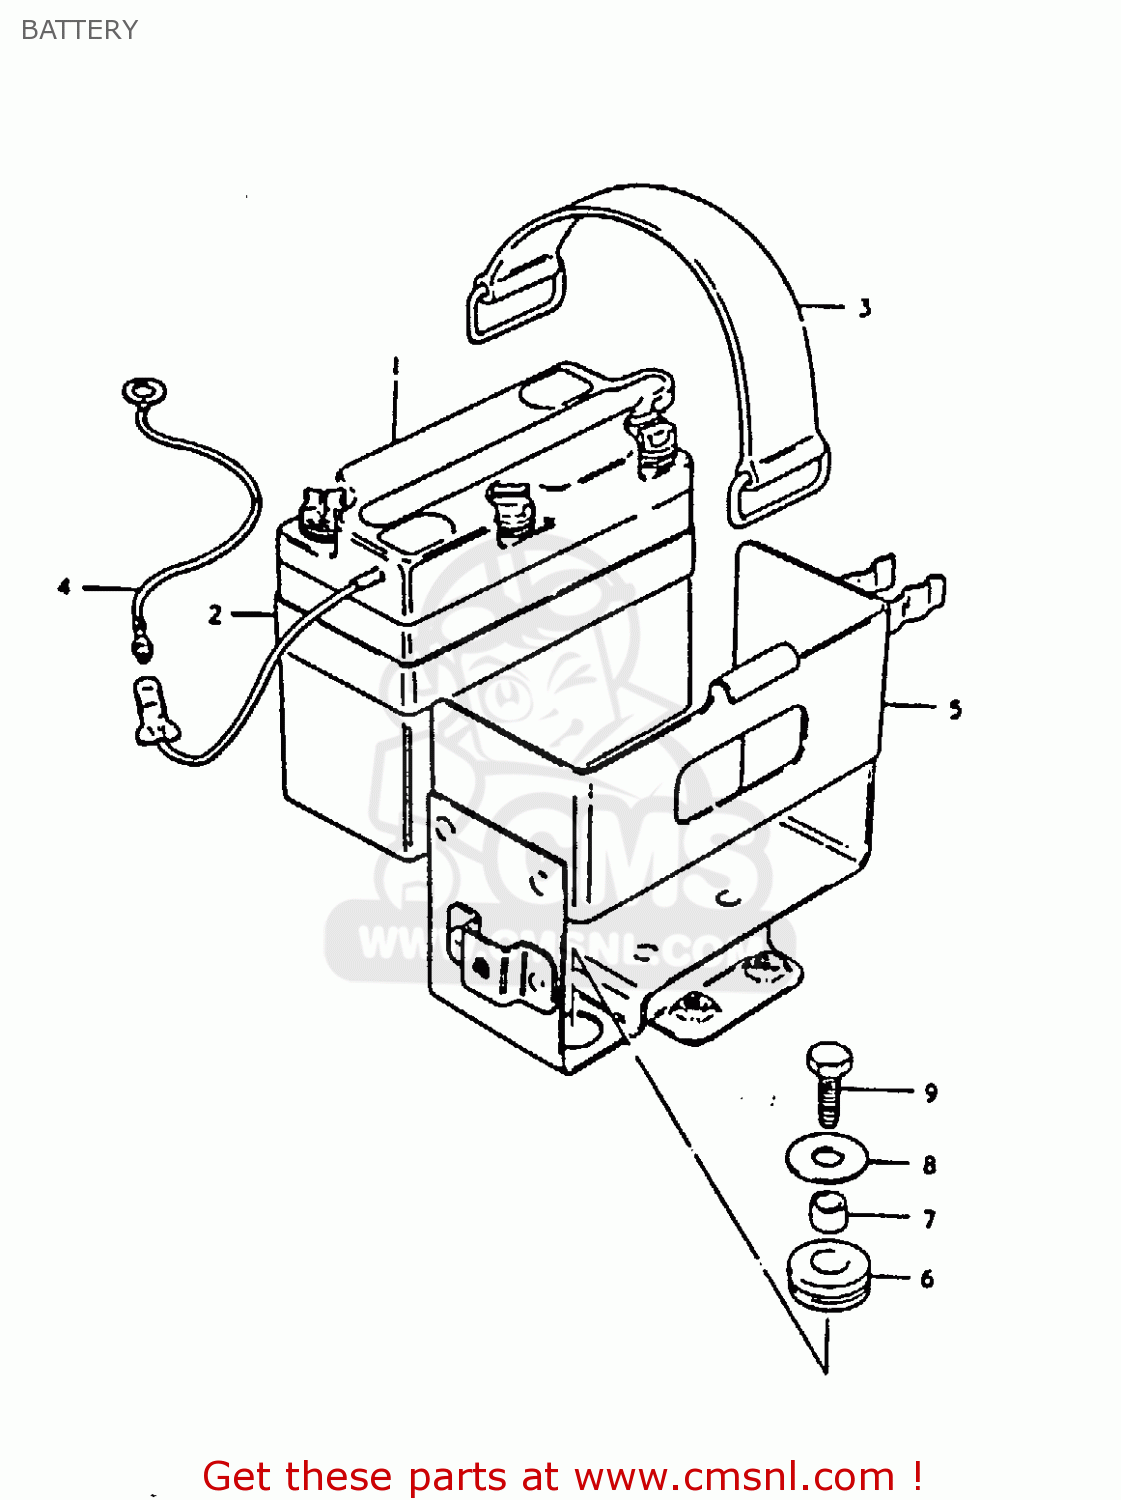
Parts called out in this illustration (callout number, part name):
1	BATTERY(6N4B-2A,6V4.2AH)
2	PROTECTOR,BATTERY
3	BAND
4	LEAD WIRE
5	HOLDER,BATTERY
6	CUSHION
7	SPACER (7X9X7)
8	WASHER (6.5X20X1.2)
9	BOLT, UPPER
